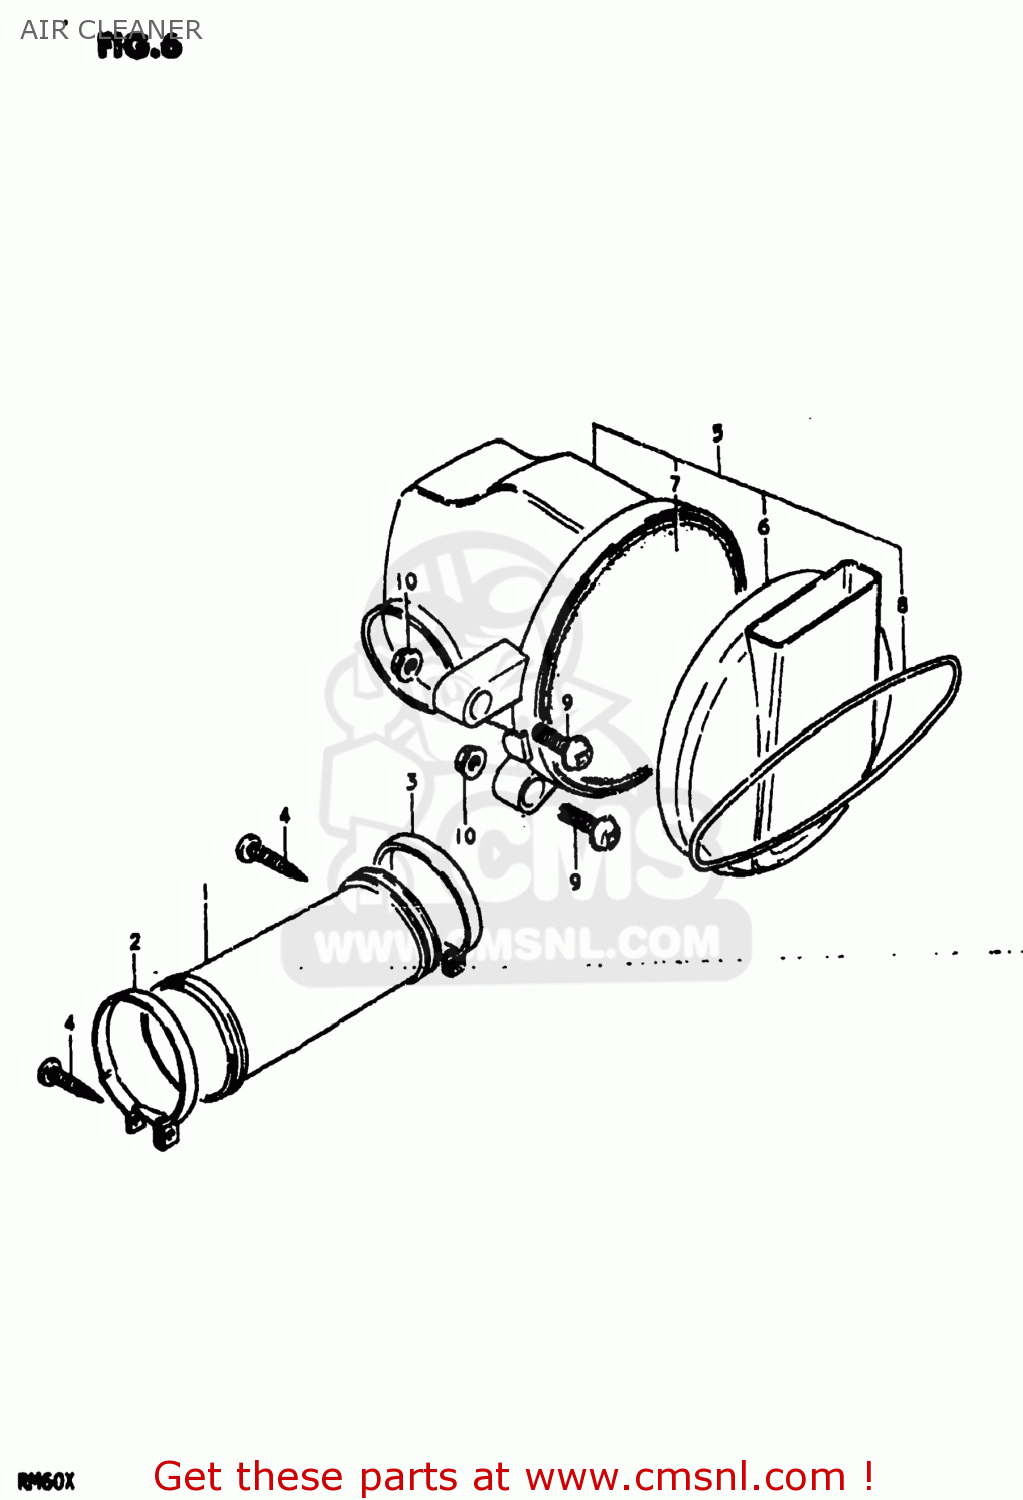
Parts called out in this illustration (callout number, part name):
1	HOSE,CARBURETOR AIR INLET
2	CLAMP
3	CLAMP
4	SCREW TAPP.
5	CLEANER ASSEMBLY,AIR
6	CAP
7	FILTER
8	O-RING,AIR CLEANER
9	SCREW
10	NUT 6MM
